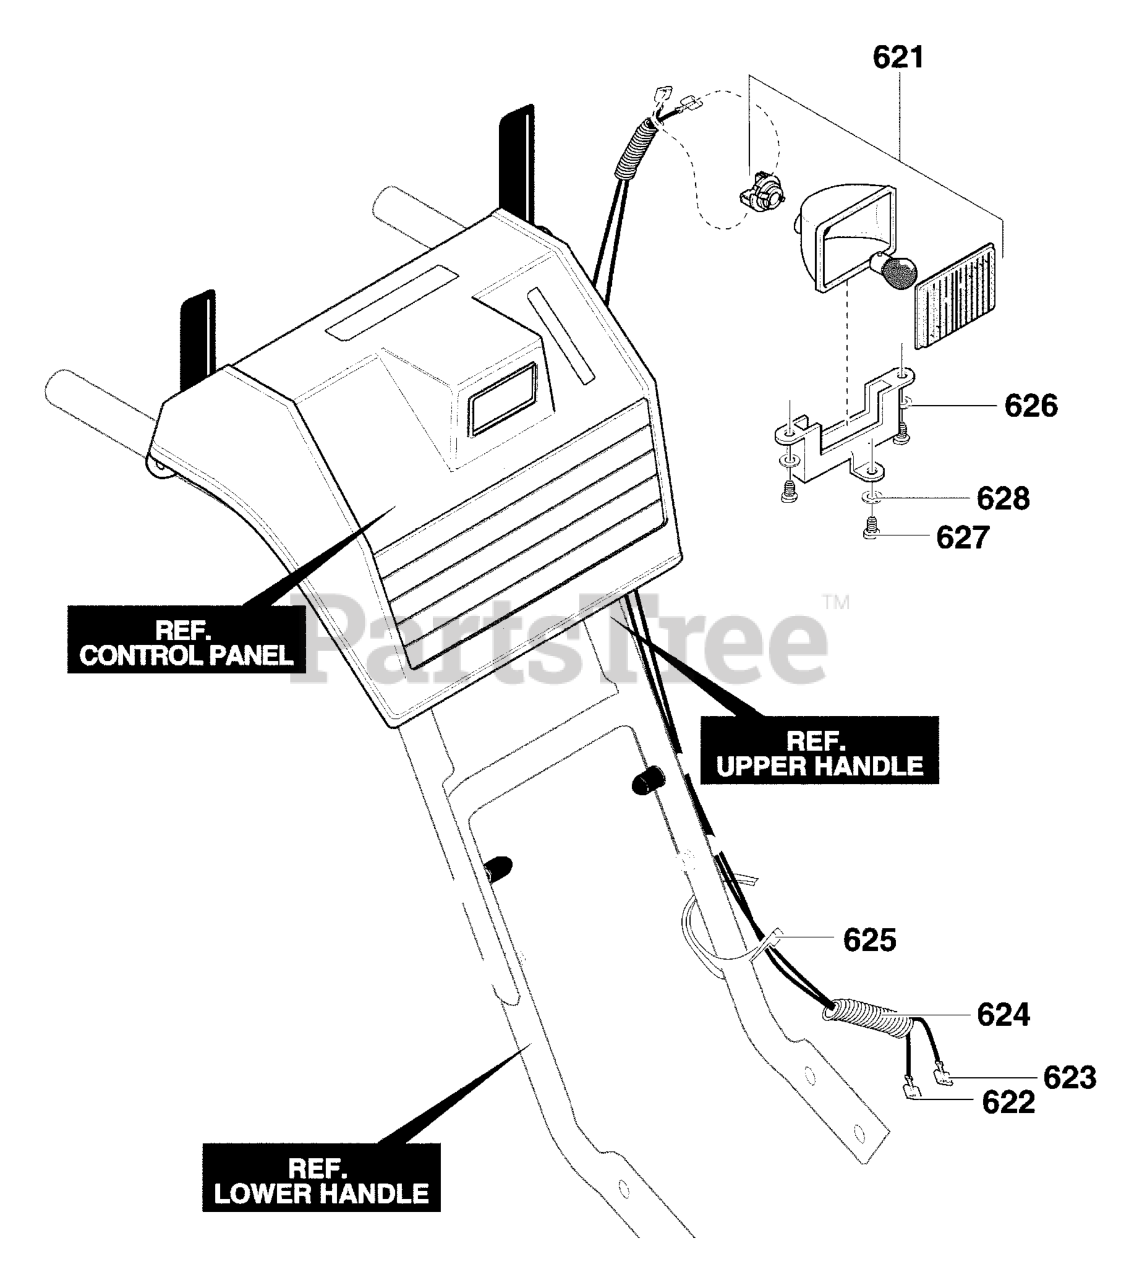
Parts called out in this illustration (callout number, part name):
621	HEADLIGHT ASSY
622	ASSY, WIRE
623	WIRE, HEADLIGHT GROUND
624	CONDUIT
625	TIE, CABLE
626	BRACKET
627	SCREW #8 X .50
628	WASHER, FLAT
